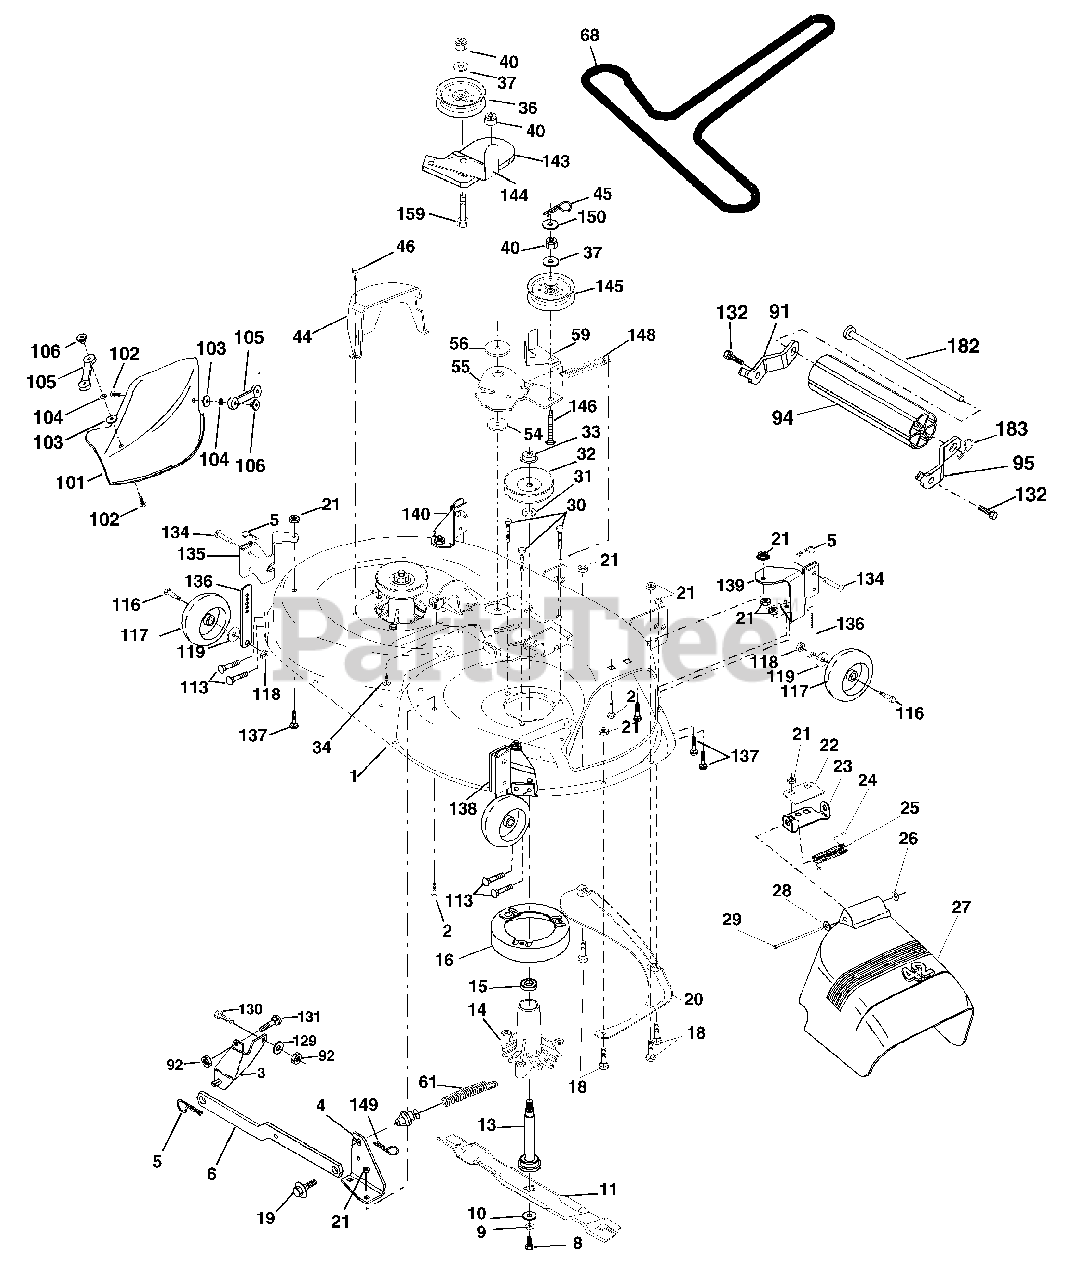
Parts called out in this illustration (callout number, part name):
1	Mower Deck Assembly, 42"
2	Bolt
3	Bracket Asm Fr. Sway Bar 3/42
4	Bracket Asm Deck 42" Sway Bar
5	Retainer Spring
6	Bar Sway Deck
8	Bolt 3/8-24 x 25 Grade 8 patched
9	Washer, Lock
10	Washer, Hardened
11	Blade, Mulching 42" Std
11	Blade Mower 42" Hi-Lift Std
13	Shaft Assembly, Mandrel, Vented
14	Housing, Mandrel, Vented
15	Bearing, Ball, Mandrel
16	Stripper, Mandrel Deck
18	Bolt, Carriage 5/16-18 x 5/8
19	Bolt, Shoulder
20	Baffle, Vortex
21	Nut
22	Stiffener Bracket
23	Bracket, Deflector Mower 42"
24	Cap, Sleeve 80 x 112 Blk Mower
25	Spring, Torsion, Deflector 2 52
26	Nut, Push Phos & Oil
27	Shield, Deflector 42" Blk
28	Washer 11/32 x 5/8 x 16 Gauge
29	Rod, Hinge 42" 6 75 W/G
30	Screw Thdrol Washer Head
31	Washer, Spacer Mower Vented
32	Pulley, Mandrel
33	Nut, Toplock Flange
34	Bolt
36	Pulley, Idler, Flat
37	Washer 13/32 x 13/16 x 16 Gauge
40	Nut
44	Guard, Mandrel, LH
45	Retainer
46	Screw, Thdrol 1/4-20 x 5/8 T
54	Washer, Hardened
55	Arm, Idler
56	Spacer, Retainer
59	Guard TUV Idler
61	Spring Ext. Elect Clutch
68	V-Belt, 42" Mower
90	Bolt Fin Hex 3/8-16 Unc x 1
91	Bracket Asm Noseroller LH
92	Nut Lock Hex W/Ins 3/8-16unc
94	Roller Nose 38 & 42
95	Bracket Asm Noseroller RH
101	Mulcher Cover
102	Screw Pan HD Phillip 10-24 x 5/8
103	Washer, Flat
104	Washer, Lock
105	Latch Assembly
106	Nut, Weld
113	Screw Tapping 5/16 - 18 x 3/4
116	Bolt, Shoulder
117	Wheel, Gauge
118	Nut Centerlock 3/8-16
119	Washer 3/8 x 7/8 x 14 Ga.
129	Washer 13/32 x 13-16 x 12 Ga.
130	Bolt Fin Hex 3/8-16 unc x 1 Gr. 5
131	Bolt RDHD 3/8-16 unc x 1
132	Screw 3/8-16 x .75
134	Pin Head Pivet
135	Brkt Asm Whl Ga. R.LH
136	Bar Adjusting Gauge Wheel
137	Bolt Carr. 5/16-18 x 5/8
138	Brkt Asm Whl Ga. R. RH
139	Brkt Asm Whl Ga. F. RH
140	Brkt Asm Whl Ga. F. LH
143	Bracket Arm Idler 42"
144	Keeper Belt 42" Clutch Cable
145	Pulley Idler Flat
146	Bolt Carriage Idler
148	Spring Return Idler
149	Retainer Spring Yellow
150	Washer 9/32 x 3/4 x 16 Ga.
159	Bolt Rdhd Sqn 3/8-16 UNC x 1-3/4
182	Rod Roller Nose
183	Retainer Spring
